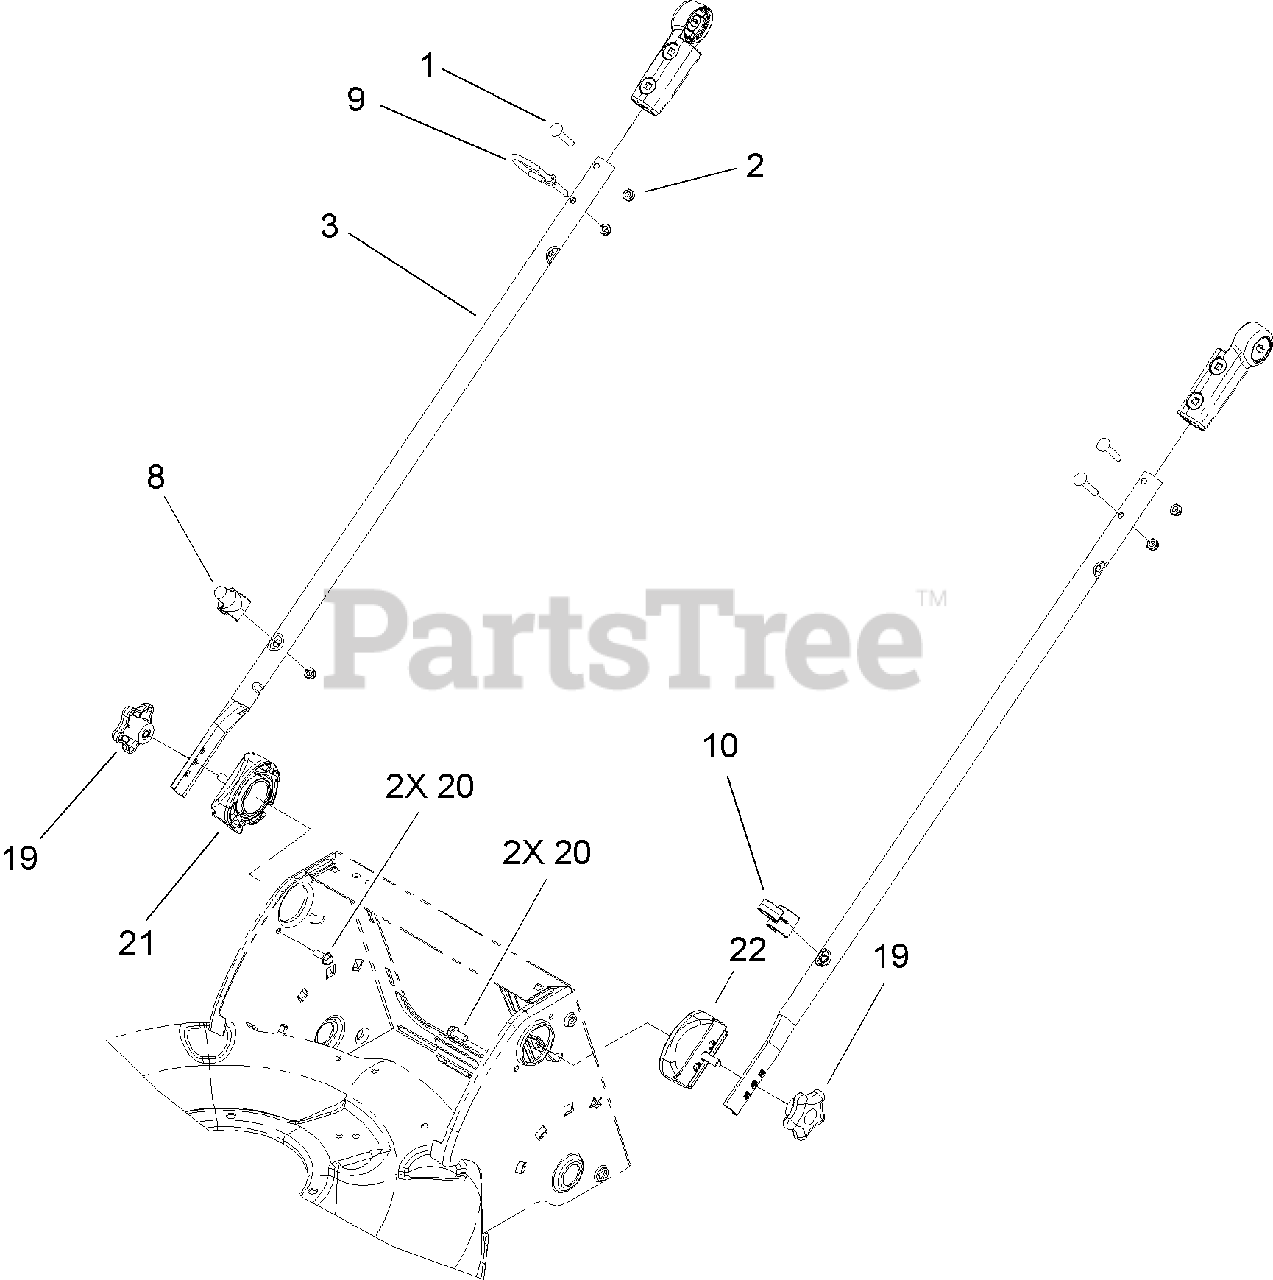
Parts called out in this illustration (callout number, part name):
1	SCREW-CARR
2	NUT-LOCK, NI
8	GUIDE-ROPE, LOWER
9	GUIDE-ROPE, UPPER
10	Guide-Cable
19	KNOB-HANDLE
20	SCREW-HWH
21	RH HANDLE MOUNT ASM
22	LH HANDLE MOUNT ASM
